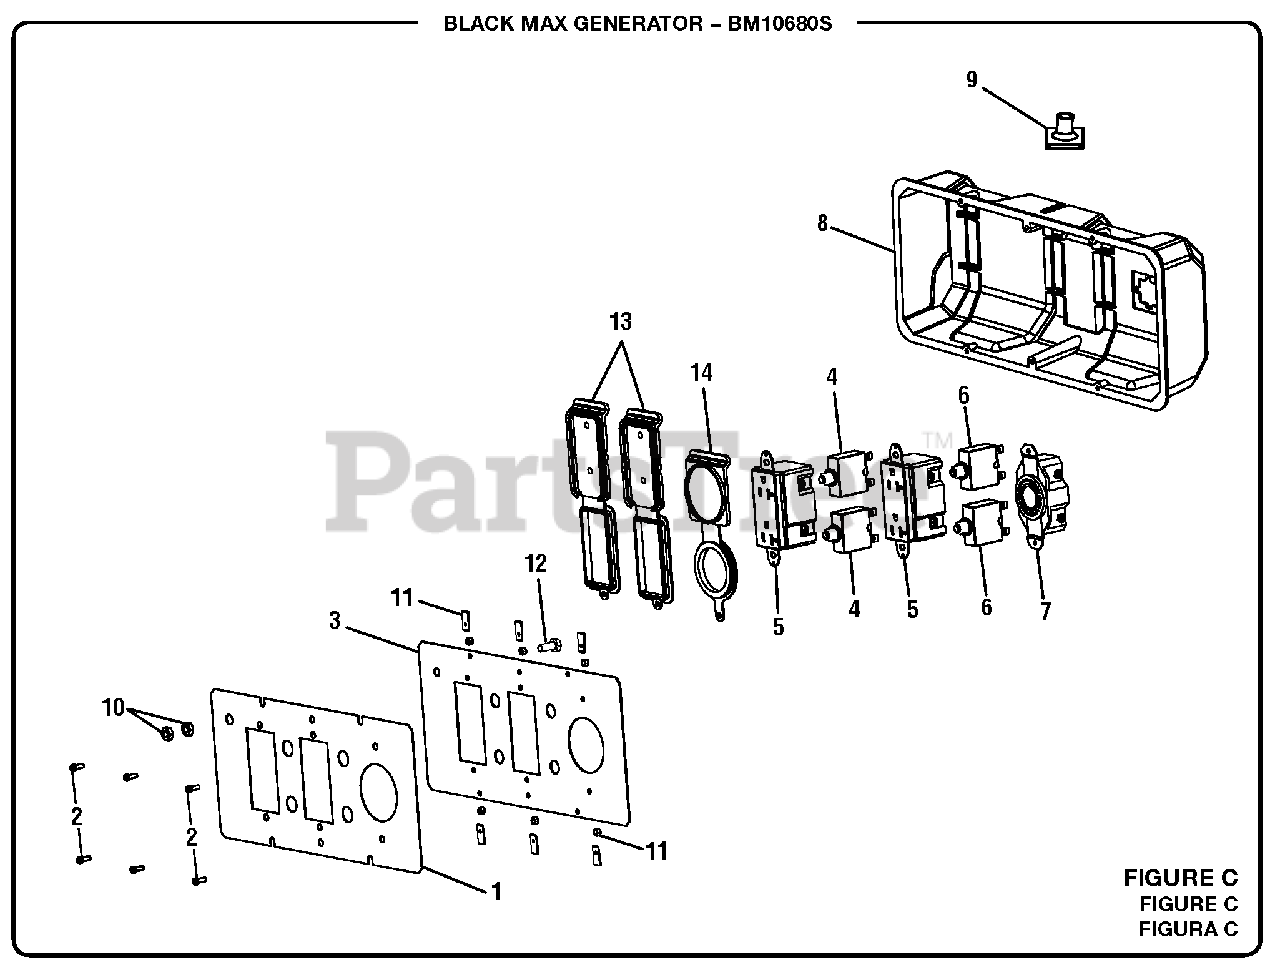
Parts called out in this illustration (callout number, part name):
1	Label (Power Outlet)
2	Screw (6-20 x 3/8 in.)
3	Front Panel
4	Circuit Breaker (20 Amp, 125 Volt)
5	120 Volt Duplex Receptacle
6	Circuit Breaker (30 Amp)
7	Twist Lock Receptacle (120/240 Volt, 30 Amp, L14-30R)
8	Control Box (Back Panel)
9	Rubber Boot (Control Panel Assembly)
12	Bolt (1/4-20 x .675 in.)
13	120 Volt Outlet Covers
14	240 Volt Outlet Covers
